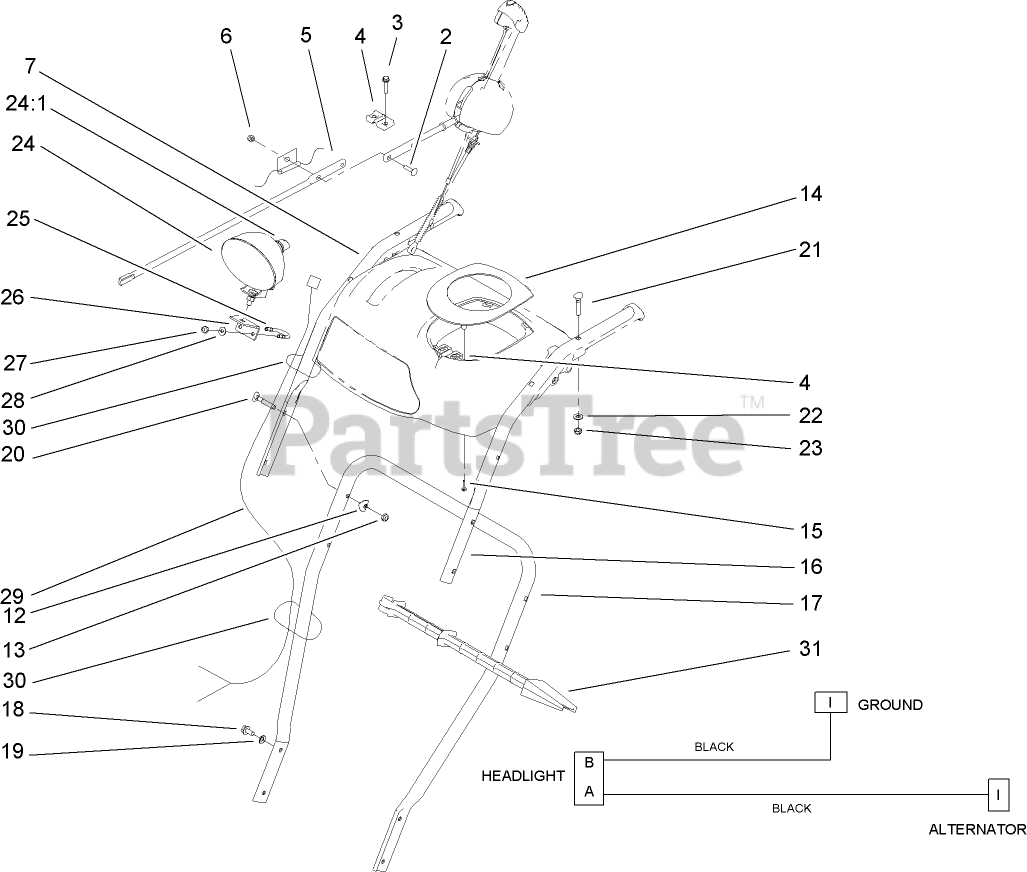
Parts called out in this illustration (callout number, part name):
2	SCREW-CARR
3	SCREW-PLASTITE
4	SUPPORT-ROD
5	ROD-CHUTE, FRONT
6	NUT-LOCK, NI
7	HANDLE-UPPER, RH
12	WASHER
13	NUT-LOCK, NI
14	COVER-PANEL, CONTROL
15	SCREW-PPH
17	HANDLE-LOWER
18	SCREW-HWHTF
19	WASHER-BELLEVILLE
20	SCREW-HANDLE
21	SCREW-HANDLE
22	WASHER-FLAT
23	NUT-LOCK, NI
24	HEADLAMP ASM
24:1	LAMP-12 VOLT
26	BRACKET-LIGHT
27	NUT-LOCK, NI
28	WASHER-FLAT
29	HARNESS-WIRE
30	TIE-CABLE
31	STICK-CLEANOUT
